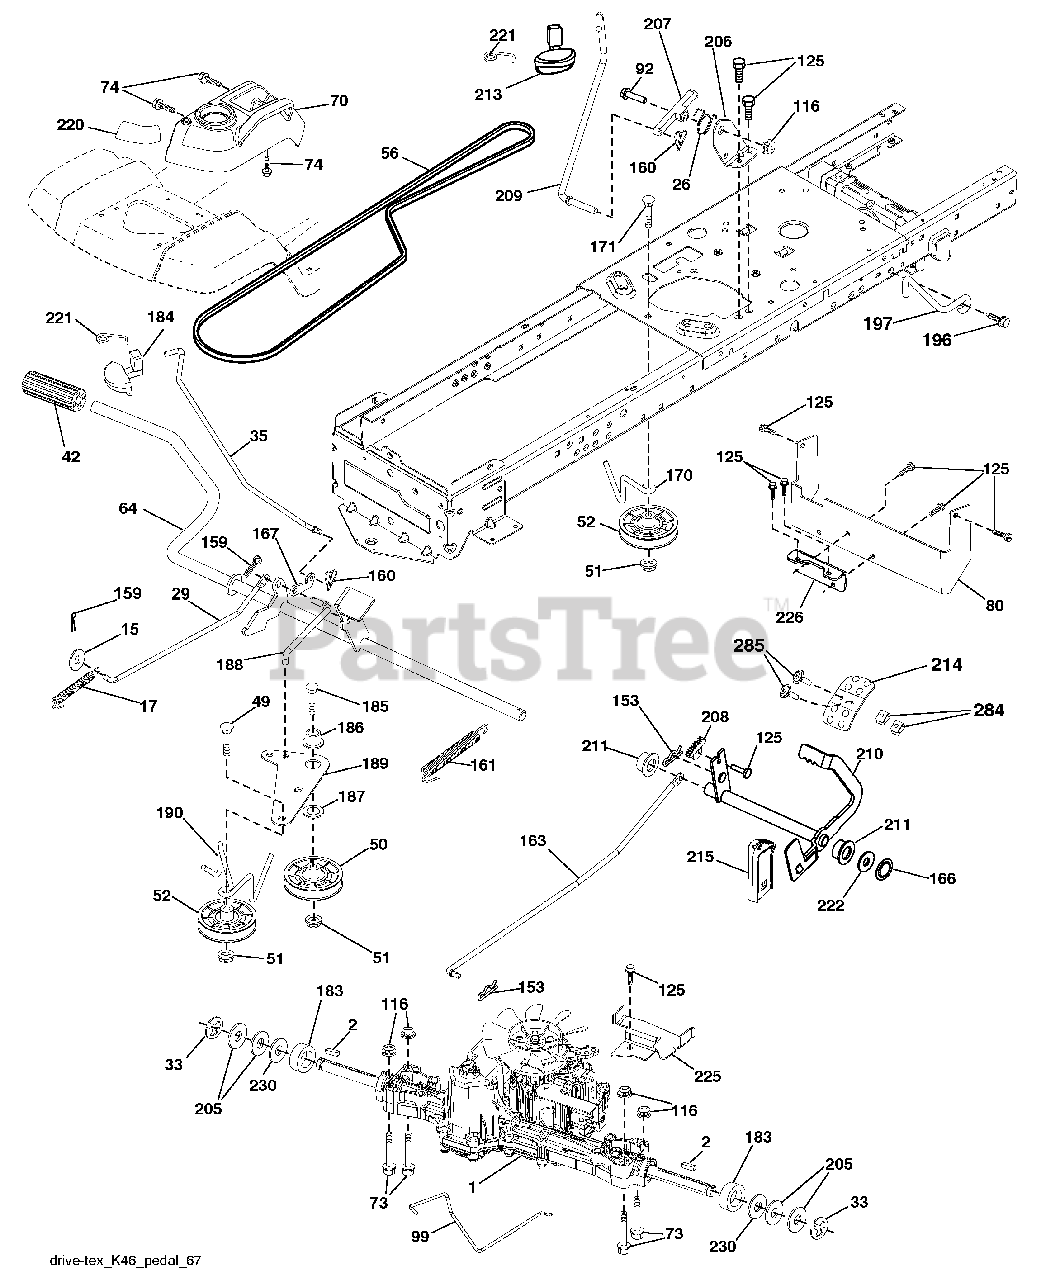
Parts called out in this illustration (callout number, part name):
1	Transaxle, TUFFTORQ K46 CR
15	Washer 13/32 x 13/16 x 16 Ga.
17	Spring, Brake
26	Spring Return Cruise
29	Rod, Brake
35	Rod, Brake, Park
42	Cover, Foot Pedal
50	Pulley Idler Flat
51	Lock Nut 3/8-16
52	Idler V-Groove 910" Offset
56	V-Belt, Drive
64	Shaft Asm. Pedal Brake Control
70	Console Asm
73	Bolt Hex Flghd 5/16-18 Gr. 5
74	Screw Hex Wsh Hi-Lo 1/4 x 1/2 unc
80	Bracket Strap Torque
92	Bolt Fin Hex 5/16-18 unc x 1.25
99	Rod Spring Bypass
116	Nut Lock Hex Flange 5/16-18
125	Screw 5/16-18 x 3/4
153	Retainer Spring
159	Pin Cotter 1/8 x 3/4
160	Retainer Clip
161	Spring, Return, Clutch
163	Rod Pedal Control
166	Nut Push
167	Latch Brake Parking
170	Keeper Belt Centerspan
171	Bolt RDHD SQNK 3/8-16 unc x 2
183	Spacer Split
184	Handle Parking Brake
185	Bolt Rdhd Sqnk 3/8-16 x 2-3/4 Gr. 5
186	Spacer Retainer
187	Washer
188	Link Clutch Ground Drive
189	Bellcrank Ground Drive
190	Keeper Bellcrank Ground Drive
196	Screw 3/8-16 x 1
197	Bracket Clutch Anti-Rotation
206	Bracket Mount Latch Cruise
207	Latch Control Cruise
208	Gear Sector Control Cruise
209	Rod Control Cruise
210	Rocker Asm. Pedal Control
211	Bearing Nylon
213	Knob Control Cruise
214	Pedal Forward
215	Pedal Reverse
220	Reflector RH
221	Retainer Spring Clip Handle
222	Washer 21/32 x 1-1/4 x 10 Ga.
225	Keeper Belt Trans.
226	Bracket Mount Touque
230	Washer Hardened
284	NutU CHNL 1/4-20 550DP .350 PNL
285	Screw PHD 1/4-20 Box Drive
